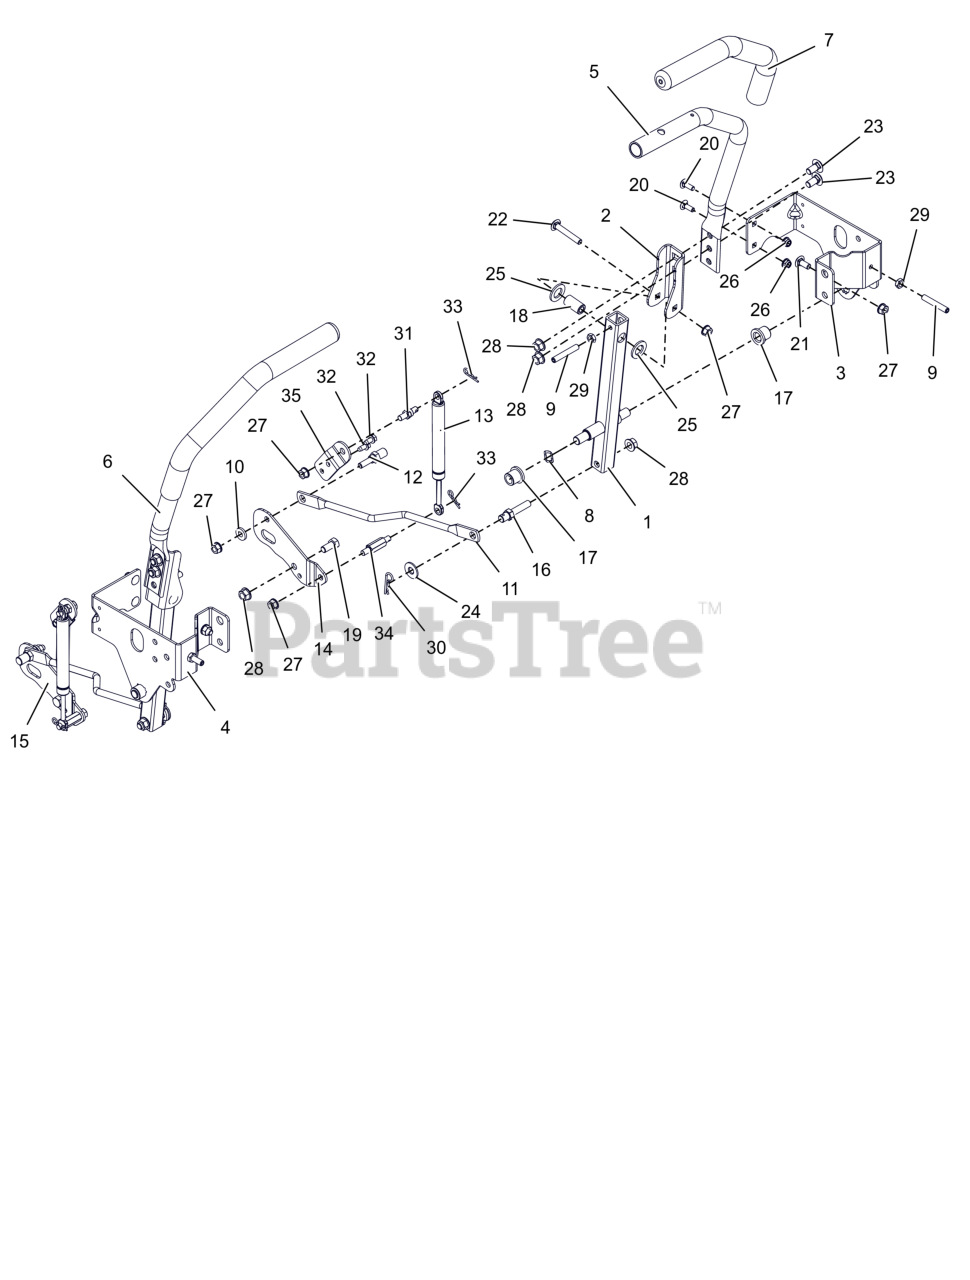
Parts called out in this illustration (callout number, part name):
1	WLDMT, LOWER CONTROL ARM (BLACK)
2	ARM, CONTROL -UPPER
3	BRKT, SPEED ADJ/SEAT PIVOT-LH (BLACK)
4	BRKT, SPEED ADJ/SEAT PIVOT-RH (BLACK)
5	WLDMT, CONTROL HANDLE -LH (BLACK)
6	WLDMT, CONTROL HANDLE - RH (BLACK)
7	GRIP, HANDLEBAR 15" FOAM
8	WAVE WASHER .531X.781X.125FH
9	SCR-SET, .312-18X2.000 SS
10	BSHG-FLG .316X.430X.225X.750
11	LINKAGE, STEERING
12	STUD, STEERING LINK-REAR
13	DAMPER, STRAIGHT MOUNT
14	PLATE, DAMPER RH
15	PLATE, DAMPER
16	STUD, STEERING LINK -FRONT
17	BHSG-FLG .500X.750X.750X.125
18	BSHG, -SLV .342 X .627 X 1.171
19	BLT,HEX .38-16X.75 G5 ZCC
20	BLT, RHSN .25-20X.750 G5 ZCC
21	BLT, RHSSN.31-18X.750 G5 ZCC
22	BLT, RHSSN .31-18X2.00 G5 ZCC
23	BTL,RHSSN .375-16 X 0.75 G5 FPB
24	WSHR,FLT .438X1.00X.083 ZCC
25	WSHR, FRICTION
26	NUT,NYL-FLG .25-20 GF ZCC
27	NUT,LK-CTR-FLG .31-18 GF ZCC
28	NUT-LK-CTR-FLG .375-16 GF ZCC
29	NUT-JAM .312-18 G2 ZCC
30	PIN, HAIR #203 .09X1.50 ZCC
31	COUPLER, DAMPER MOUNT
32	SCR-TAP .25-20X.50 HWH ZCC
33	PIN, HAIR #213 .08X1.19 ZCC
34	COUPLER, DAMPER MOUNT (LOWER)
35	PLATE, DAMPER TOP MOUNTING (BLACK)
